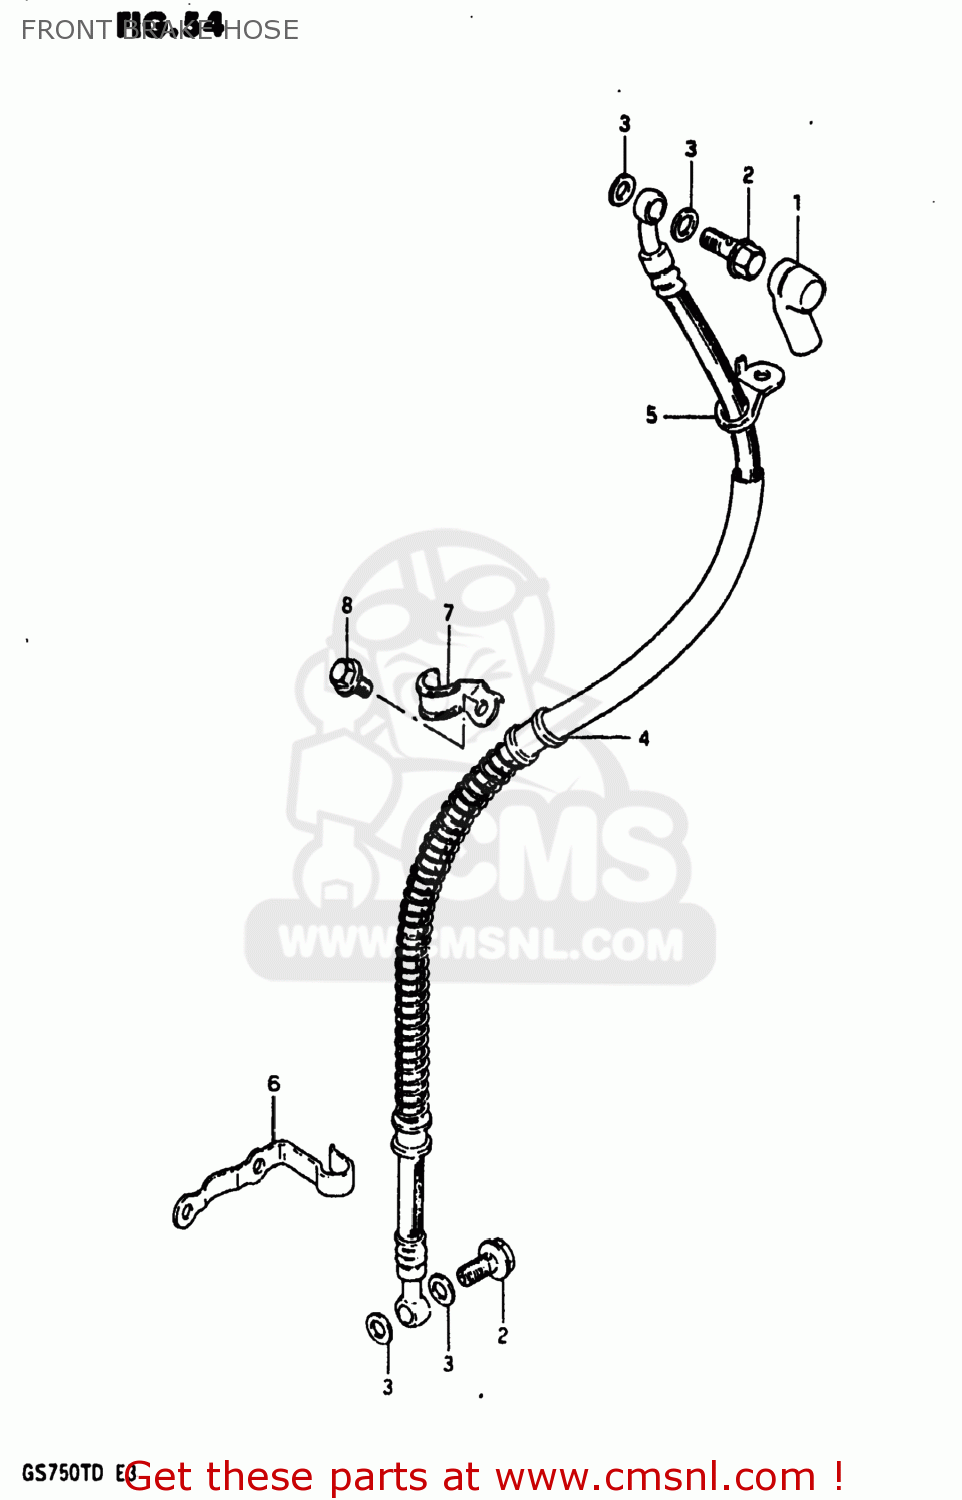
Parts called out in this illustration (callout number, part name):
1	BOOT,MASTER CYLINDER
2	BOLT,UNION
3	WASHER
4	HOSE,FRONT BRAKE
5	GUIDE,BRAKE HOSE NO.1
6	GUIDE,BRAKE HOSE NO.2
7	GUIDE,BRAKE HOSE NO.3
8	BOLT
